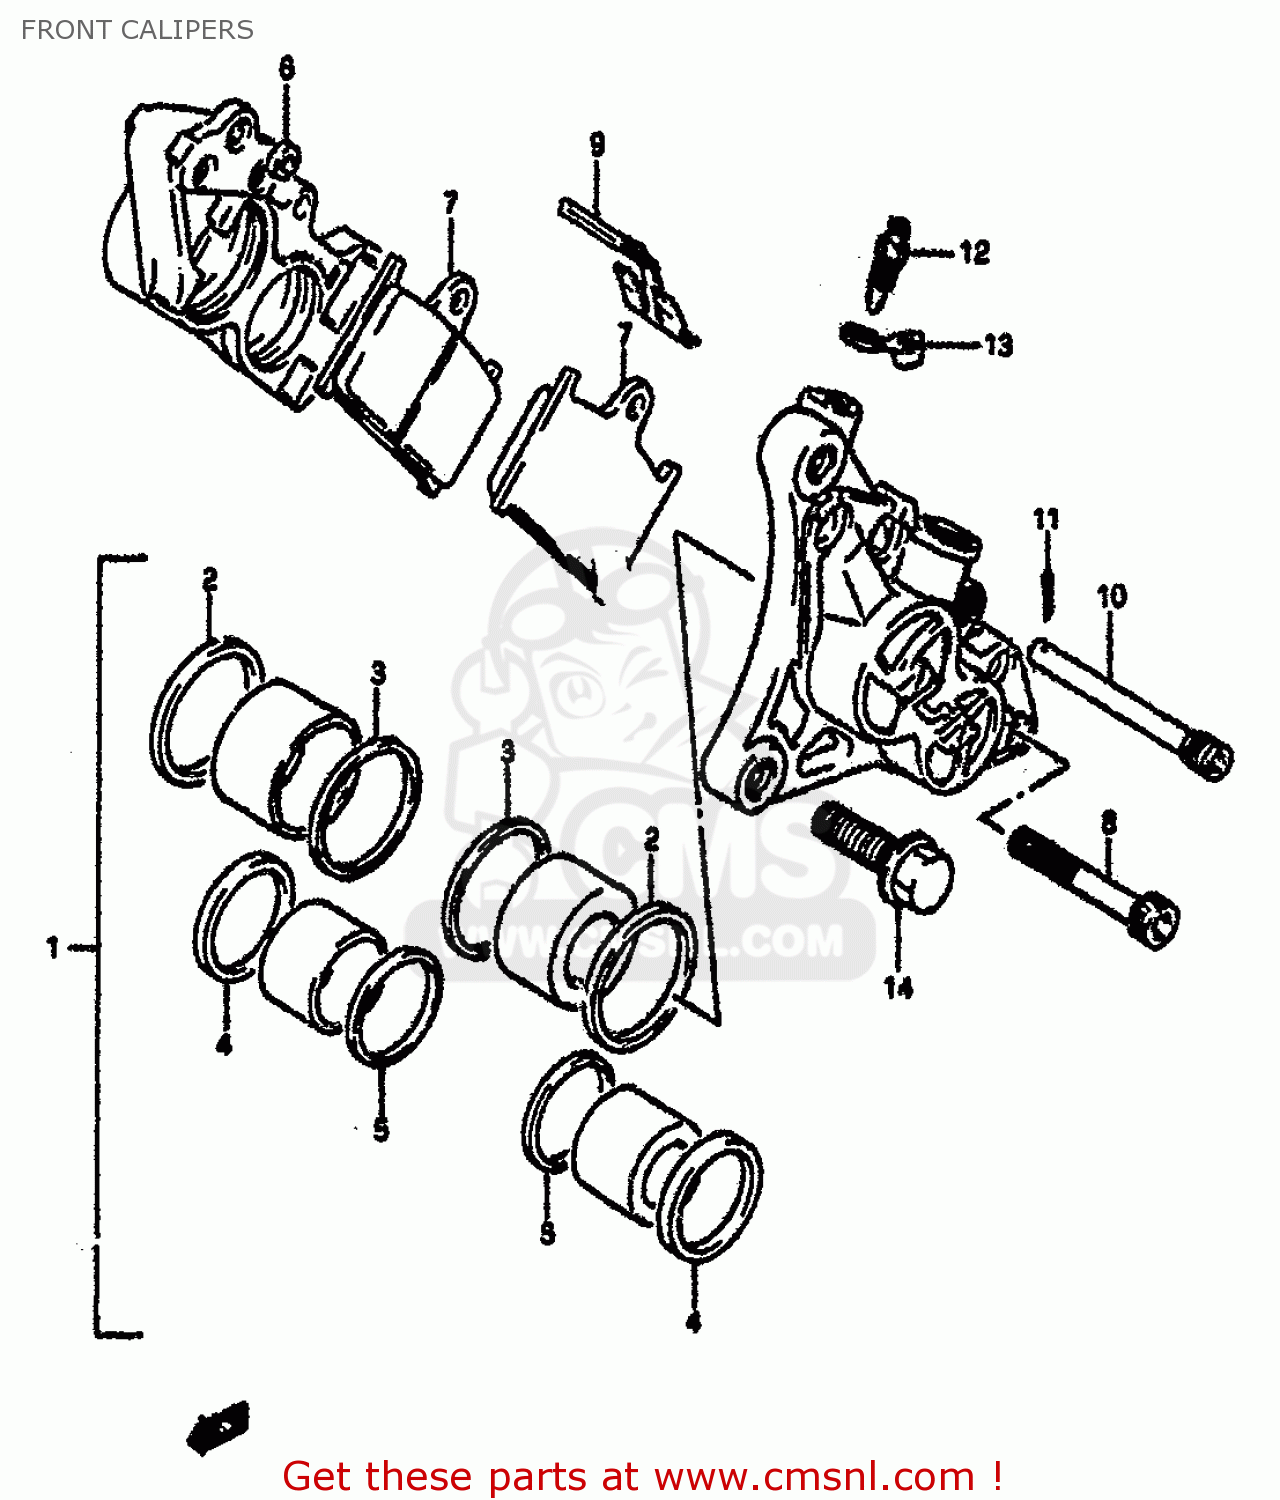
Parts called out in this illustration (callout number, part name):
1	PISTON SET
2	SEAL,PISTON
3	BOOT,PISTON
4	SEAL,PISTON
5	SEAL
6	SEAL
7	PAD
8	BOLT
9	SPRING
10	PIN,HANGER
11	COTTER PIN
12	BLEEDER
13	CAP,BLEEDER
14	BOLT 10X30
